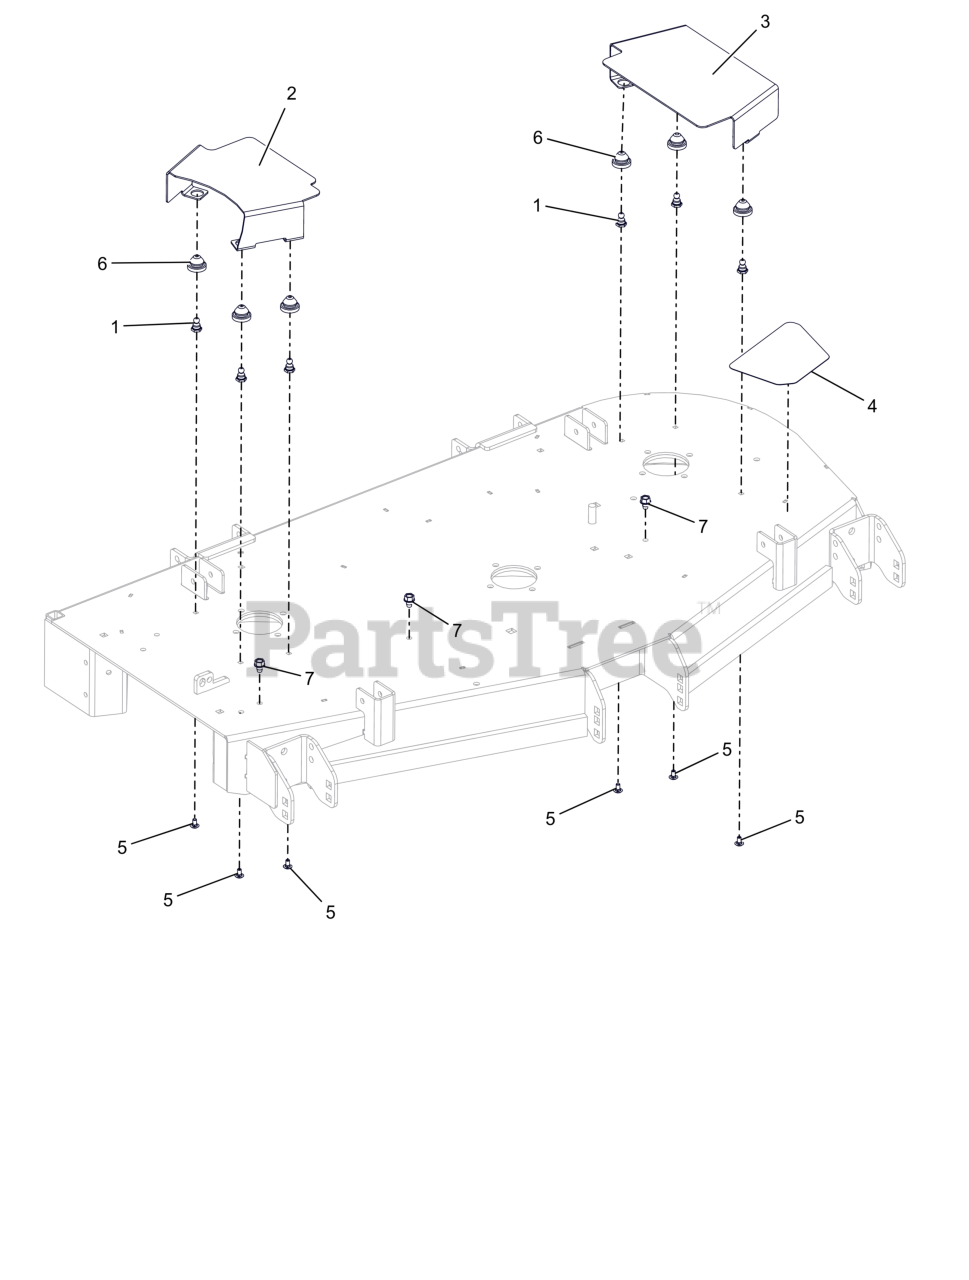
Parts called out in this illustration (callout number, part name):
1	STUD, BALL FEMALE .250-20 THREAD
2	GUARD, RH DECK BELT (RED)
3	GUARD, LH DECK BELT (RED)
4	GRIP, STEP ANTI SKID
5	BLT, RHSSN.25-20X.500 G5 ZCC
6	COUPLING, RUBBER PUSH-IN
7	SCR,TAP .375-16X.50 HWH TR ZCC
